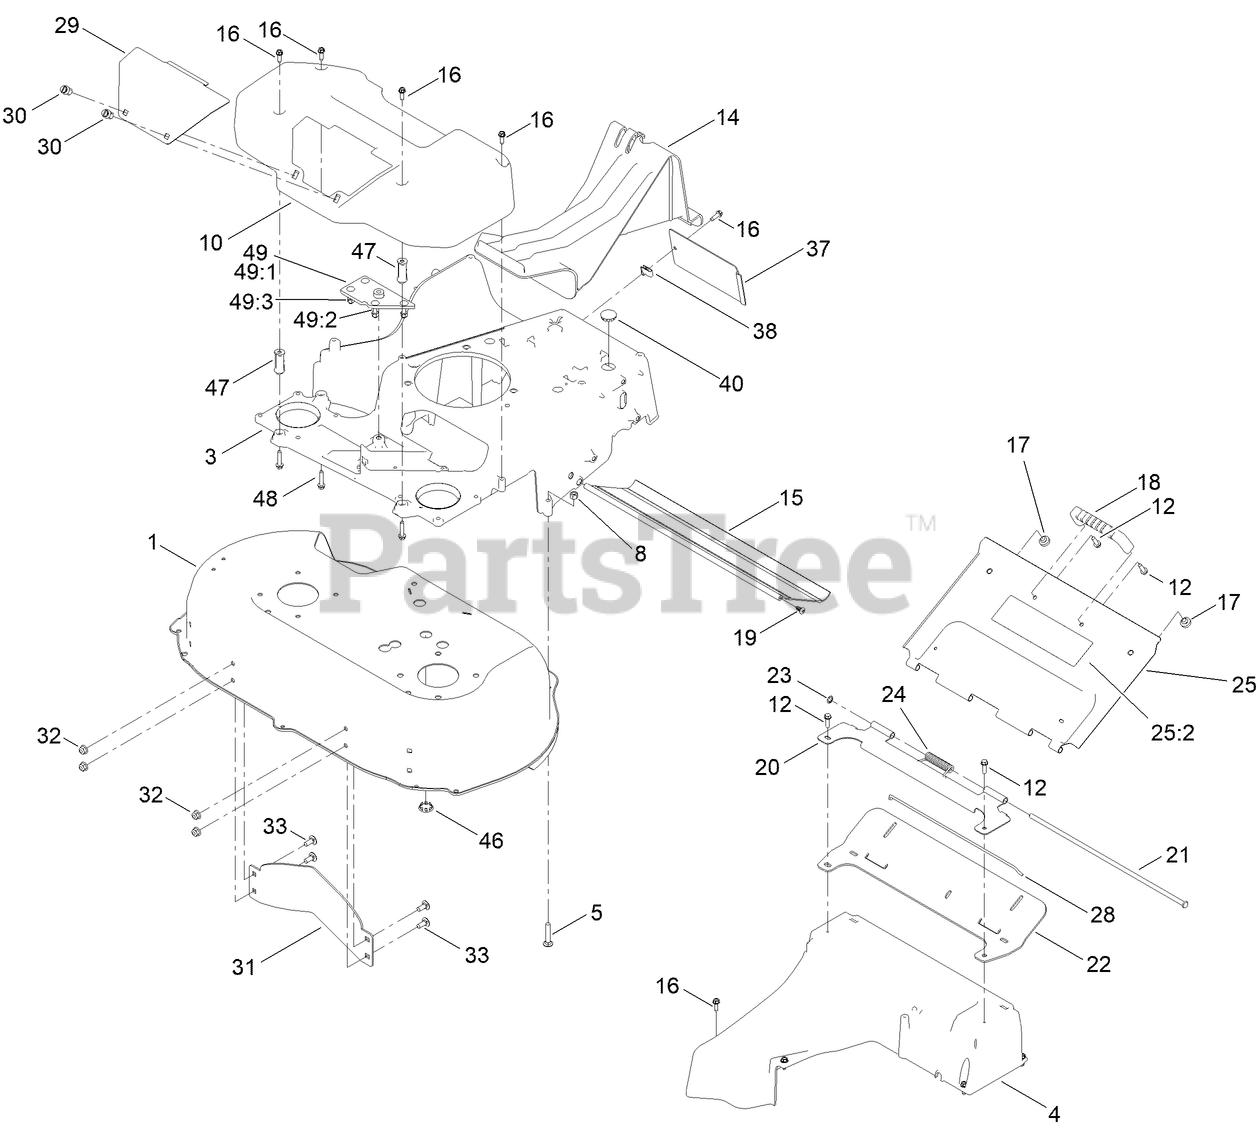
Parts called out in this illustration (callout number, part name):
1	HOUSING ASM
3	FRAME-30"
5	BOLT-CAR
8	NUT-LOCK, NI
10	COVER-BELT
12	SCREW-HWH
14	PLUG-MULCH
15	SHIELD-TRAILING
16	SCREW-HWHTF
17	BUMPER
18	HANDLE-DOOR
19	SCREW-PTH
20	BRACKET-HINGE
21	PIN-HINGE
22	SEAL-DOOR
23	RING-RETAINING
24	SPRING-TORSION, COVER
25	REAR DOOR ASM
25:2	DECAL-WARNING
28	CLIP-SEAL
29	PANEL-ACCESS
30	FASTENER
31	BAFFLE-CONTROL
32	NUT-HF, NI
33	SCREW-CARR
37	COVER-FRAME
40	PLUG-BUTTON
46	PLUG-BUTTON
47	SPACER-FRAME, 30 IN.
48	SCREW-HWHTF
49	FRAME-PLATE KIT
49:1	PLATE-FRAME, ASM
49:2	SCREW-CARR
49:3	NUT-LOCK, NI
